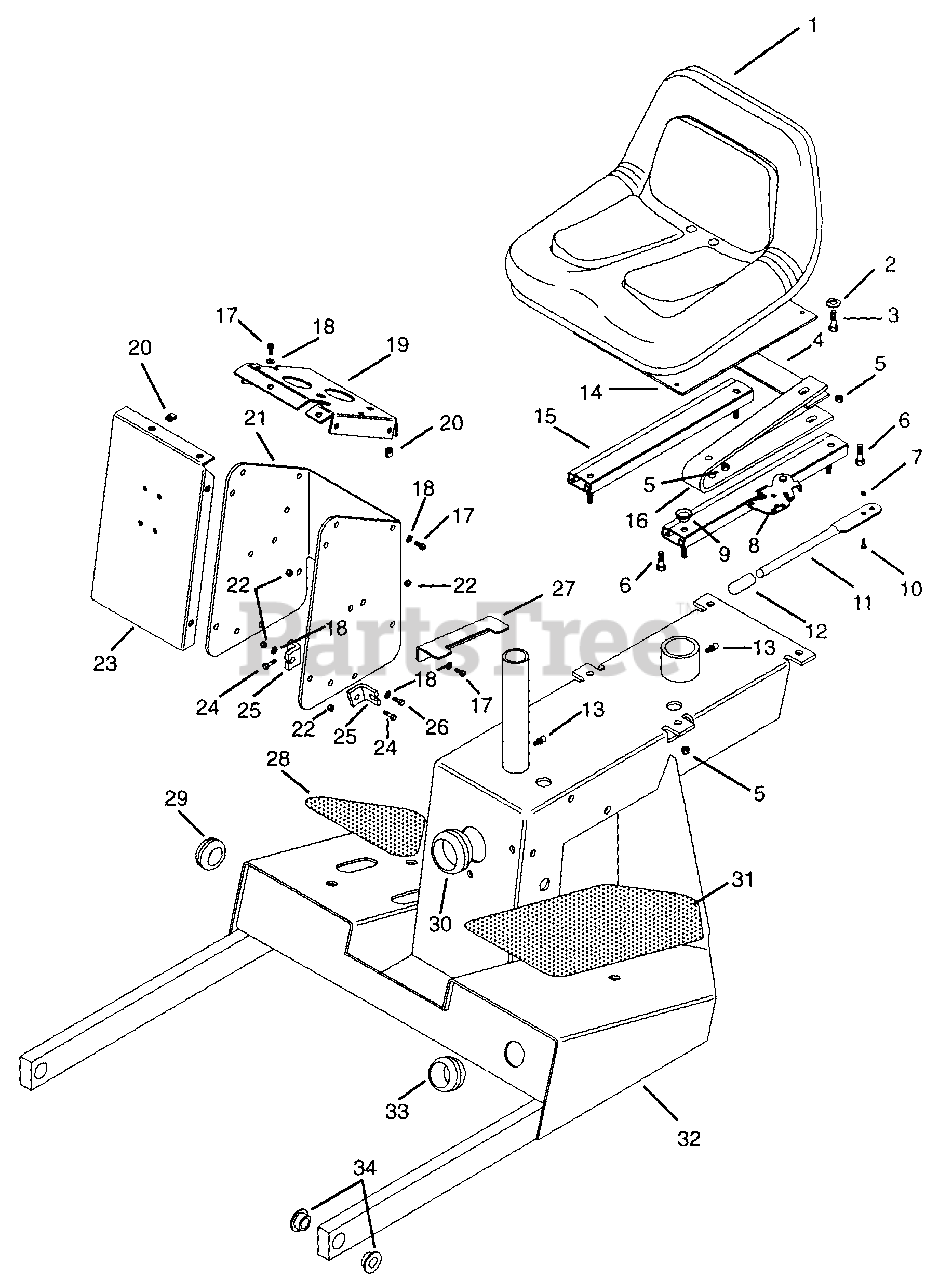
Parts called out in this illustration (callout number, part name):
1	Seat High Back
2	Washer-Lock .313 x .078
3	Bolt-Hex .31-18 x 1.00 Grade 5
4	Bracket, Seat
5	Nut-Locking-Nylon .312-18
6	Bolt-Hex .31-18 x 1.38
7	Nut-Locking 10-24
8	Adjuster, Seat w/Latch
9	Seat Slide Spacer
10	Screw-Machine 10-24 x .625
11	Seat Slide Handle
12	Tip-Brake Lock Lever
13	Fitting-Lube .25-28 x .256
14	Plate
15	Adjuster, Seat
16	Spring, Seat
17	Screw-Machine .25-20
18	Washer-Flat-Steel .281 x .625 x .065
19	Panel, Instrument
20	Nut-Retainer .25-20 x .56
21	Support, Panel
22	Nut-Locking-Nylon .250-20
23	Cover, Panel
24	Bolt-Hex .25-20 x 1.00 Grade 5
25	Bracket, Cable
26	Bolt-Hex .25-20 x .75 Grade 5
27	Stop, Brake Lever
28	Cover, Footboard Left Hand
29	Grommet 1.25 x 1.5 x 1.81
30	Grommet
31	Cover, Footboard Right Hand
32	Weldment, Rear Frame
33	Grommet 1.50 x 1.75 x 2.12
34	Bushing-Flange .762 x 1.0 x .580 x 1.48
